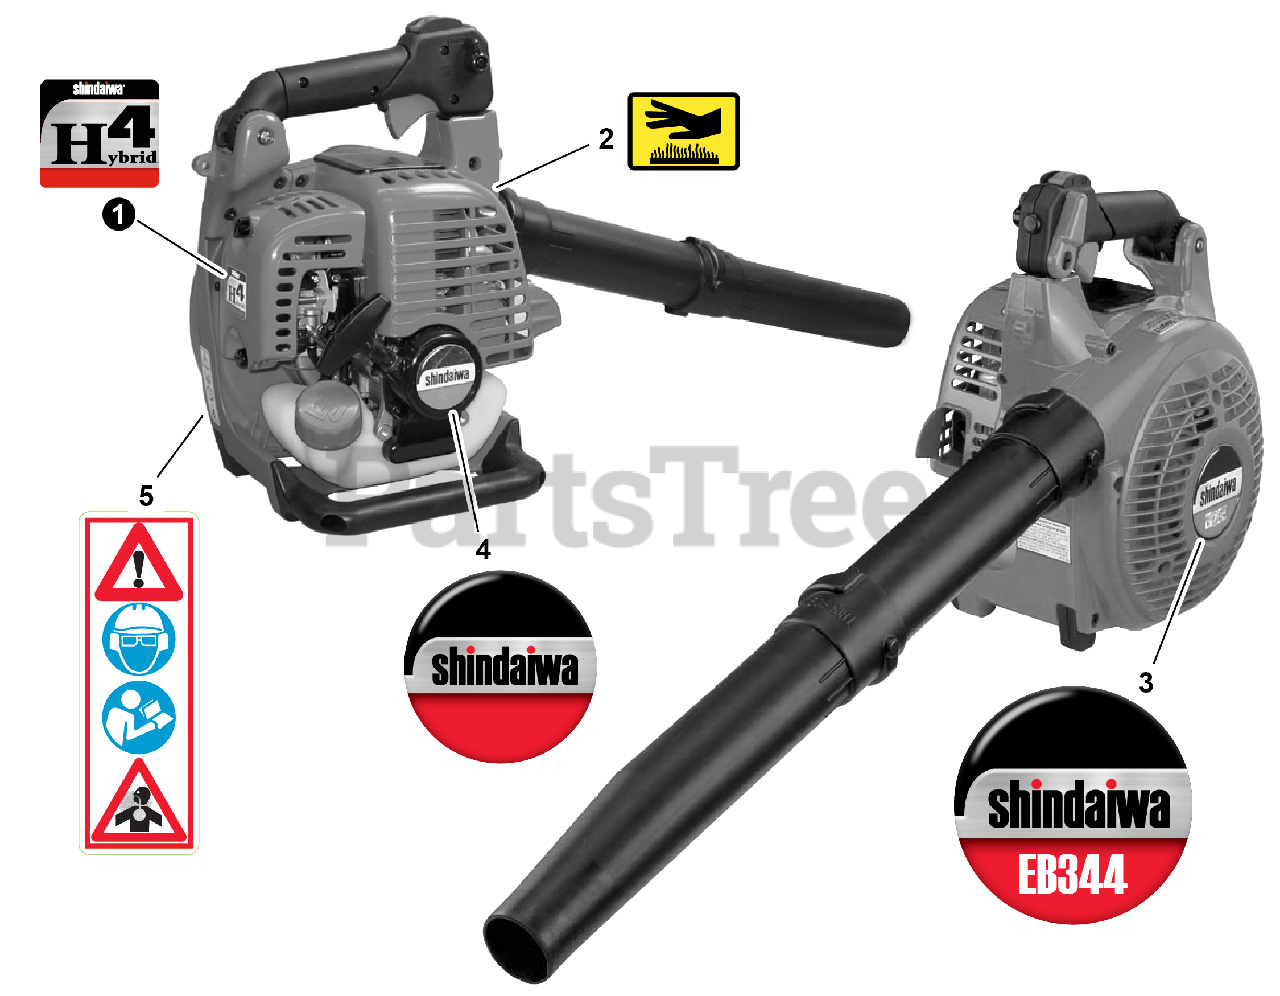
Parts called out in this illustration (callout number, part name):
1	LABEL, shindaiwa H4
2	LABEL, CAUTION - HOT
3	LABEL, EB344
4	LABEL, SHINDAIWA
5	LABEL, CAUTION
